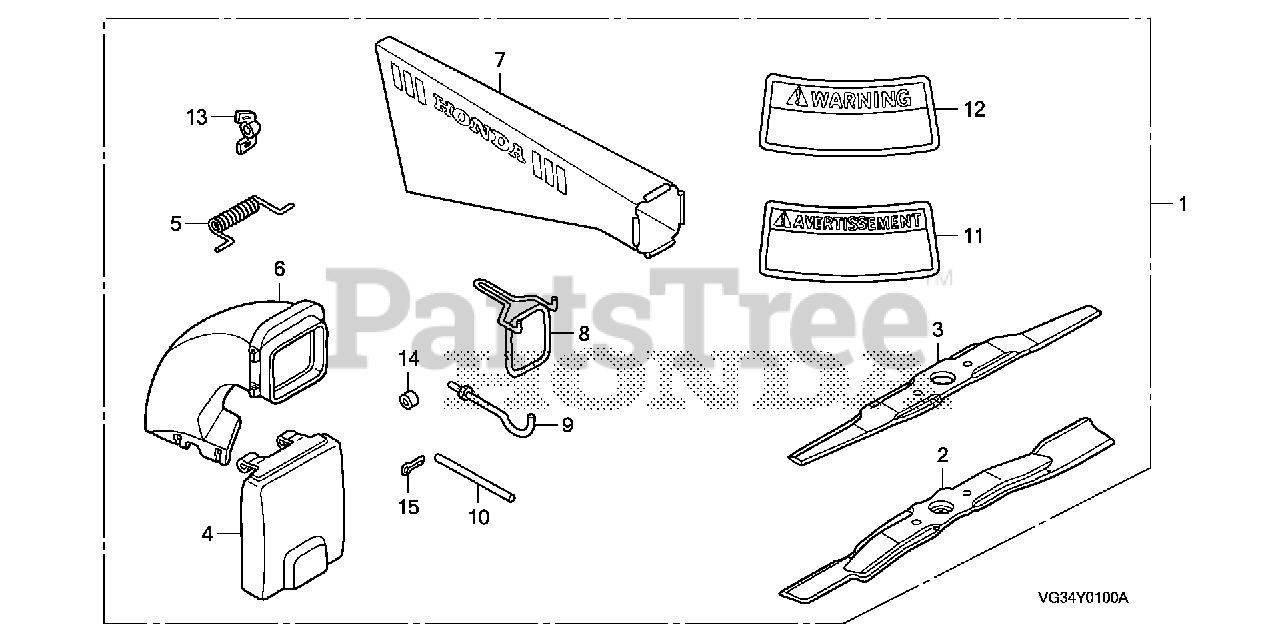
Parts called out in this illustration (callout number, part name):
1	BAG KIT, GRASS (NOT AVAILABLE)
2	BLADE, ROTARY
3	BLADE, ROTARY (UPPER) (PCD=88MM)
4	GUARD, DISCHARGE (NOT AVAILABLE)
5	SPRING, GUARD RETURN
6	ADAPTER, GRASS BAG (NA USE ALT:06813-VG3-020)
7	FABRIC, GRASS BAG
8	FRAME, BAG
9	LEVER, GRASS BAG
10	PIPE, GRASS BAG
11	LABEL, DISCHARGE GUARD WARNING (FRENCH) (N/A FOR USA)
12	LABEL, DISCHARGE GUARD WARNING (ENGLISH)
13	WINGNUT (1/4-20) (NOT AVAILABLE)
14	COLLAR, LEVER
15	PIN, SPLIT (2.0X12)
